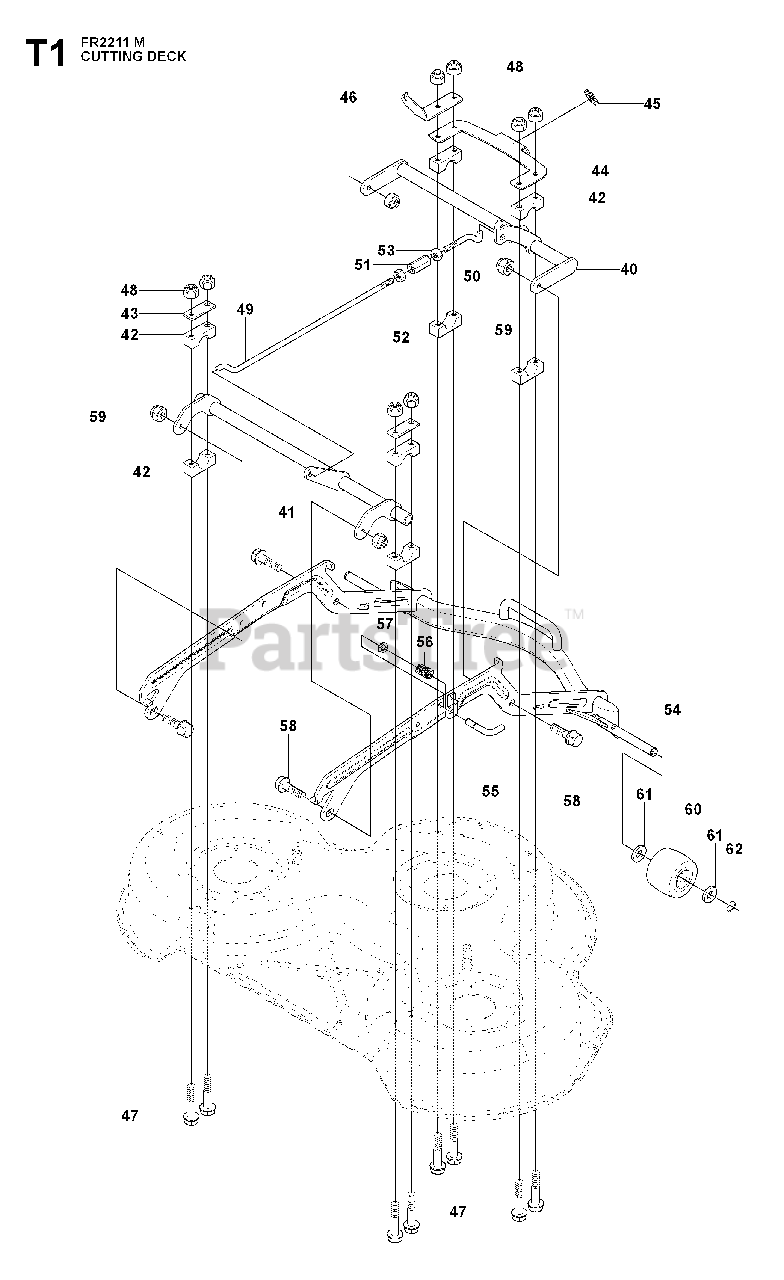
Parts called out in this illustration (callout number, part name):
48	LOCKNUT M8
59	LOCKNUT M8
60	DECK ROLLER, FRONT
62	RETAINING RING SGA 15
